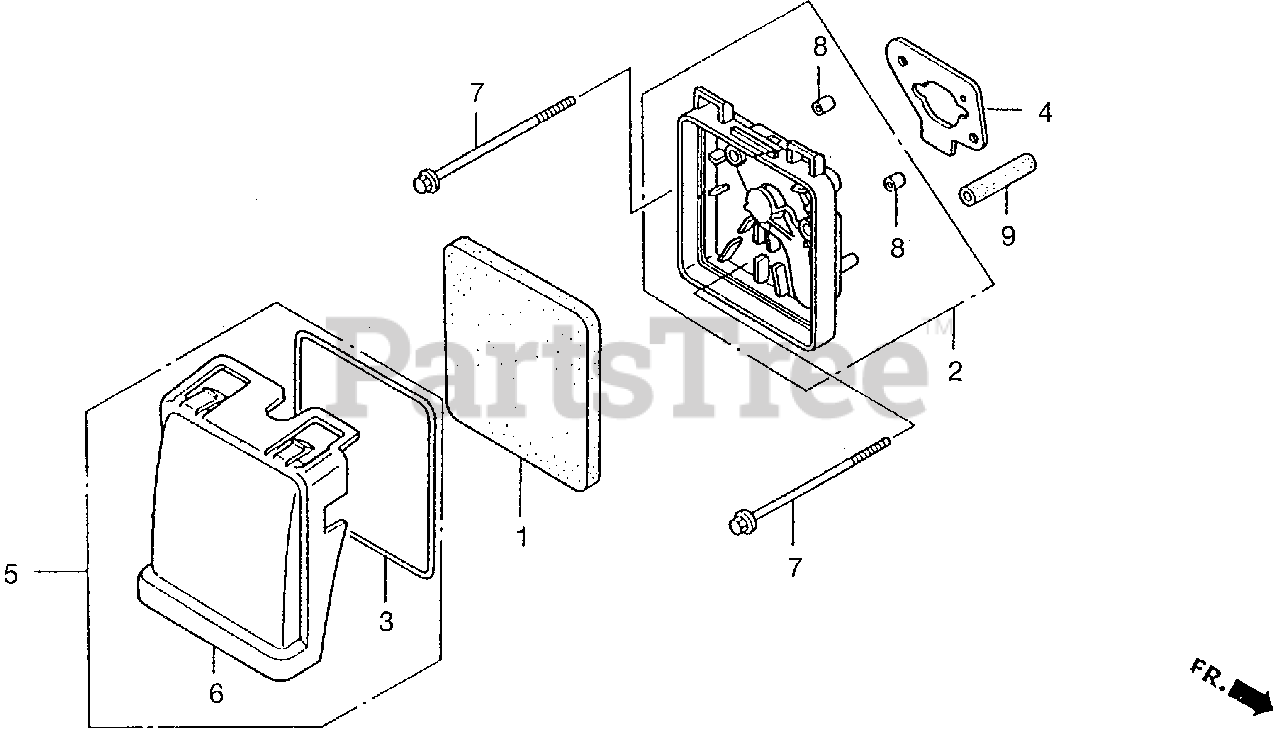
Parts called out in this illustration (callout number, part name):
1	ELEMENT, AIR CLEANER
2	HOUSING, AIR CLEANER
3	SEAL, AIR CLEANER
4	GASKET, AIR CLEANER
5	COVER, AIR CLEANER
6	COVER, AIR CLEANER
7	BOLT, FLANGE (5X75)
8	COLLAR, AIR CLEANER
9	BULK HOSE, VACUUM (7X3000) (7X75)
